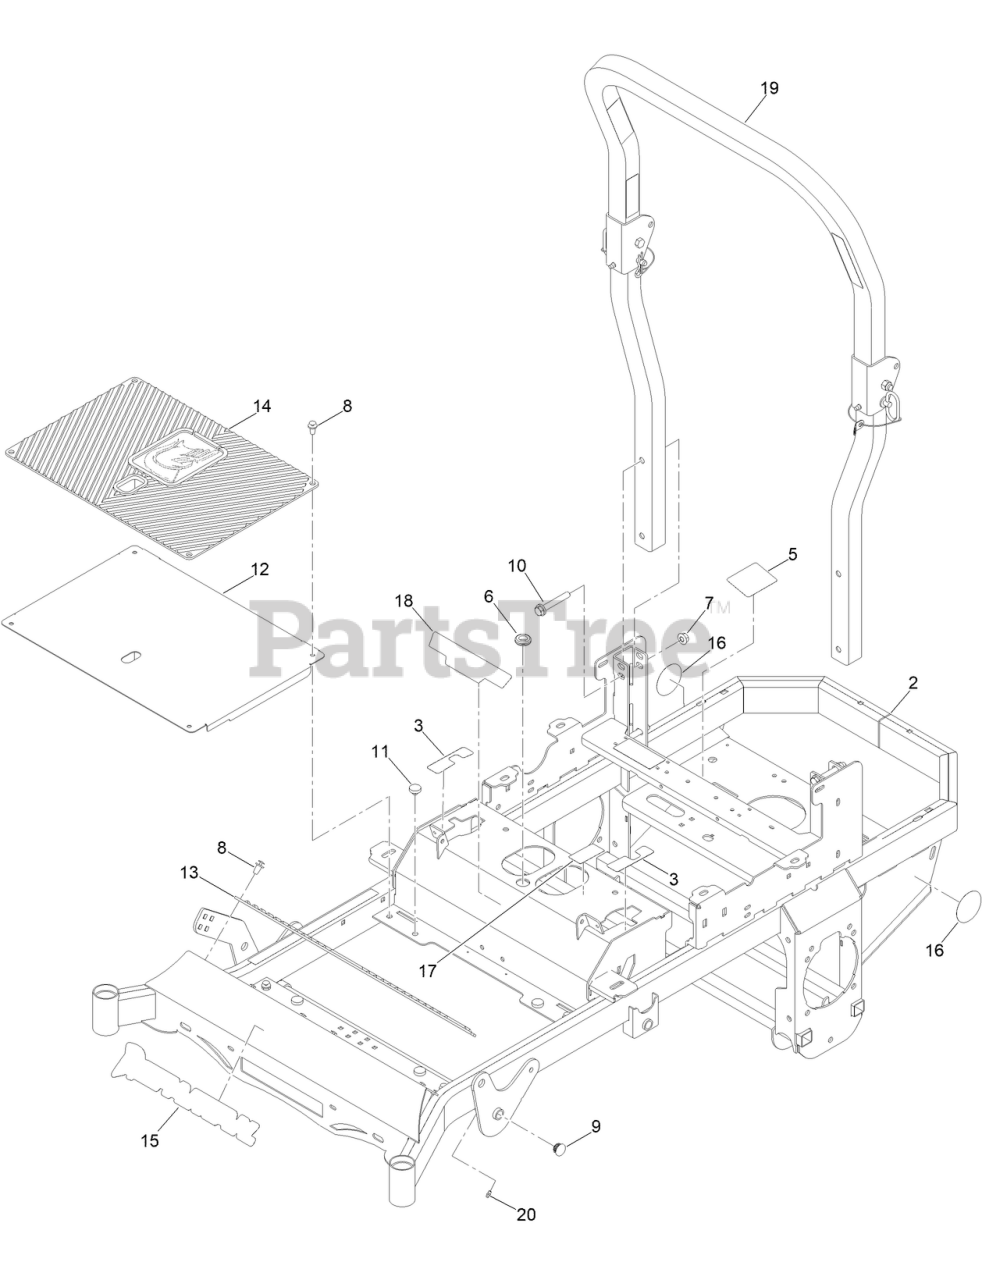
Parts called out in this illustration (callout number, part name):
2	FRAME ASM W/DECALS
3	DECAL-MOTION CONTROL
5	DECAL-PUMP BELT ROUTING-PARKER
6	GROMMET-RUBBER
7	1/2-13 HEX STOVER LOCKNUT GR C ZINC
8	8MM PUSH TYPE RETAINER NYLON BLACK
9	1IN ROUND TUBE PLUG
11	PUSH-IN RUBBER BUMPER MWR FLOOR
12	RZ FLOORBOARD PAINTED
13	MWR RUBBER FOOT REST MAT
14	MWR LOGO FLOOR MAT
15	MWR FT SPARTAN LOGO
16	MWR PARKER PUMP DECAL
17	MWR SEAT WEIGHT CAPACITY DECAL
18	RZ-HD W/GT TRAC DECAL
19	MWR FOLD DOWN ROPS
19	SPARTAN FOLDING ROPS BOXED
20	1/4 DRIVE TYPE STRAIGHT GREASE FITTNG ZC
